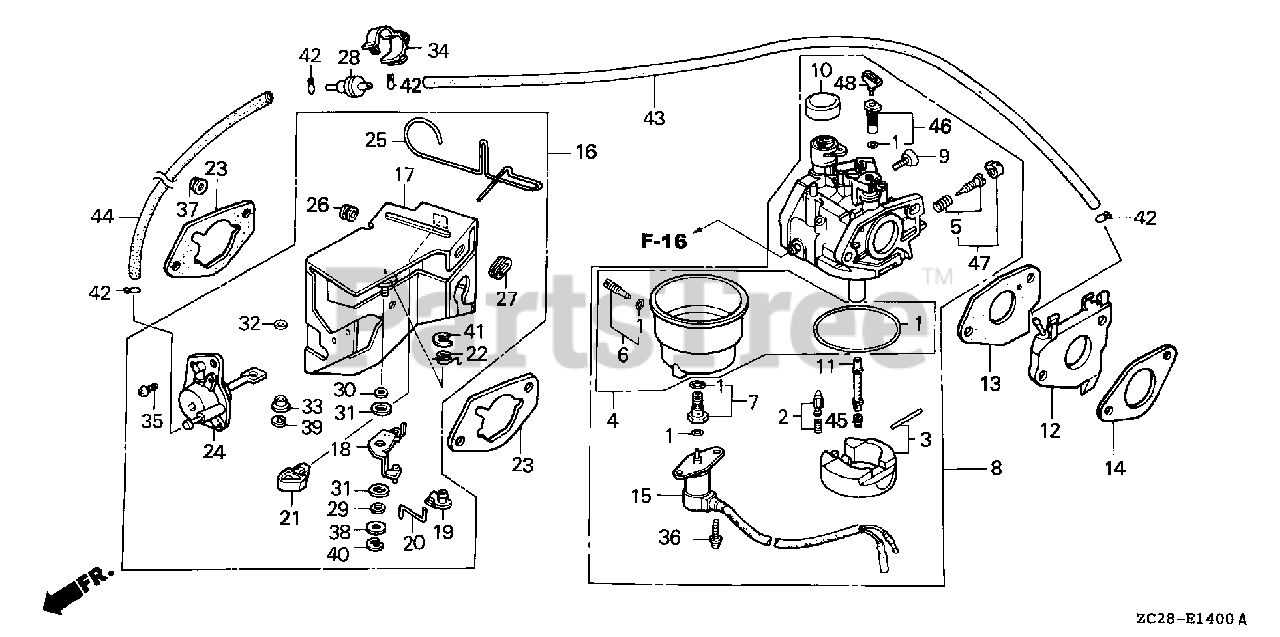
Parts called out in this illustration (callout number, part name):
1	GASKET SET
2	VALVE SET, FLOAT
4	CHAMBER SET, FLOAT
5	SCREW SET, PILOT
6	SCREW SET, DRAIN (CARBURETOR NO.)
7	SCREW SET B
8	CARBURETOR ASSY. (BE37B B)
8	CARBURETOR ASSY. (BE82B B)
8	CARBURETOR ASSY. (BE82B C)
9	SCREW, THROTTLE STOP
10	CAP, CHOKE LEVER DUST
11	NOZZLE, MAIN
12	INSULATOR, CARBURETOR
13	GASKET, CARBURETOR
14	GASKET, INSULATOR
15	VALVE ASSY., SOLENOID
16	STAY ASSY., MANUAL CHOKE
17	STAY, SOLENOID
18	LEVER, CHOKE
19	JOINT, ROD
20	ROD, CHOKE
21	STOPPER, CHOKE ROD
22	SPRING, MANUAL CHOKE
23	GASKET, AIR CLEANER
24	DIAPHRAGM ASSY.
25	ROD, CHOKE CONTROL
26	GROMMET, CHOKE ROD
27	GUIDE, CHOKE ROD
28	VALVE, DASHPOT CHECK
29	BUSH, ARM PIVOT
30	WASHER, CHOKE LEVER
31	SEAL, CHOKE LEVER
32	WASHER, THRUST (2.7X8)
33	COLLAR, LEVER
34	CLIP, WIRE HARNESS
35	SCREW, PAN (5X12)
36	SCREW-WASHER (5X12)
37	NUT, FLANGE (6MM)
38	WASHER, PLAIN (5MM)
39	E-RING (2MM)
40	E-RING (4MM)
41	E-RING (7MM)
42	CLIP, TUBE (B7)
43	BULK HOSE, VACUUM (3.5X8000) (3.5X75)
44	BULK HOSE, VACUUM (3.5X8000) (3.5X130)
45	JET, MAIN (#92) Use up to Engine SN BE37B A.
45	JET, MAIN (#95) Use up to Engine SN BE37B A.
45	JET, MAIN (#98)
45	JET, MAIN (#95) Use from Engine SN BE82B A.
45	JET, MAIN (#98) Use from Engine SN BE82B A.
45	JET, MAIN (#100)
46	JET SET, PILOT (#35)
46	JET SET, PILOT (#45)
47	SCREW SET
48	COLLAR, SET
